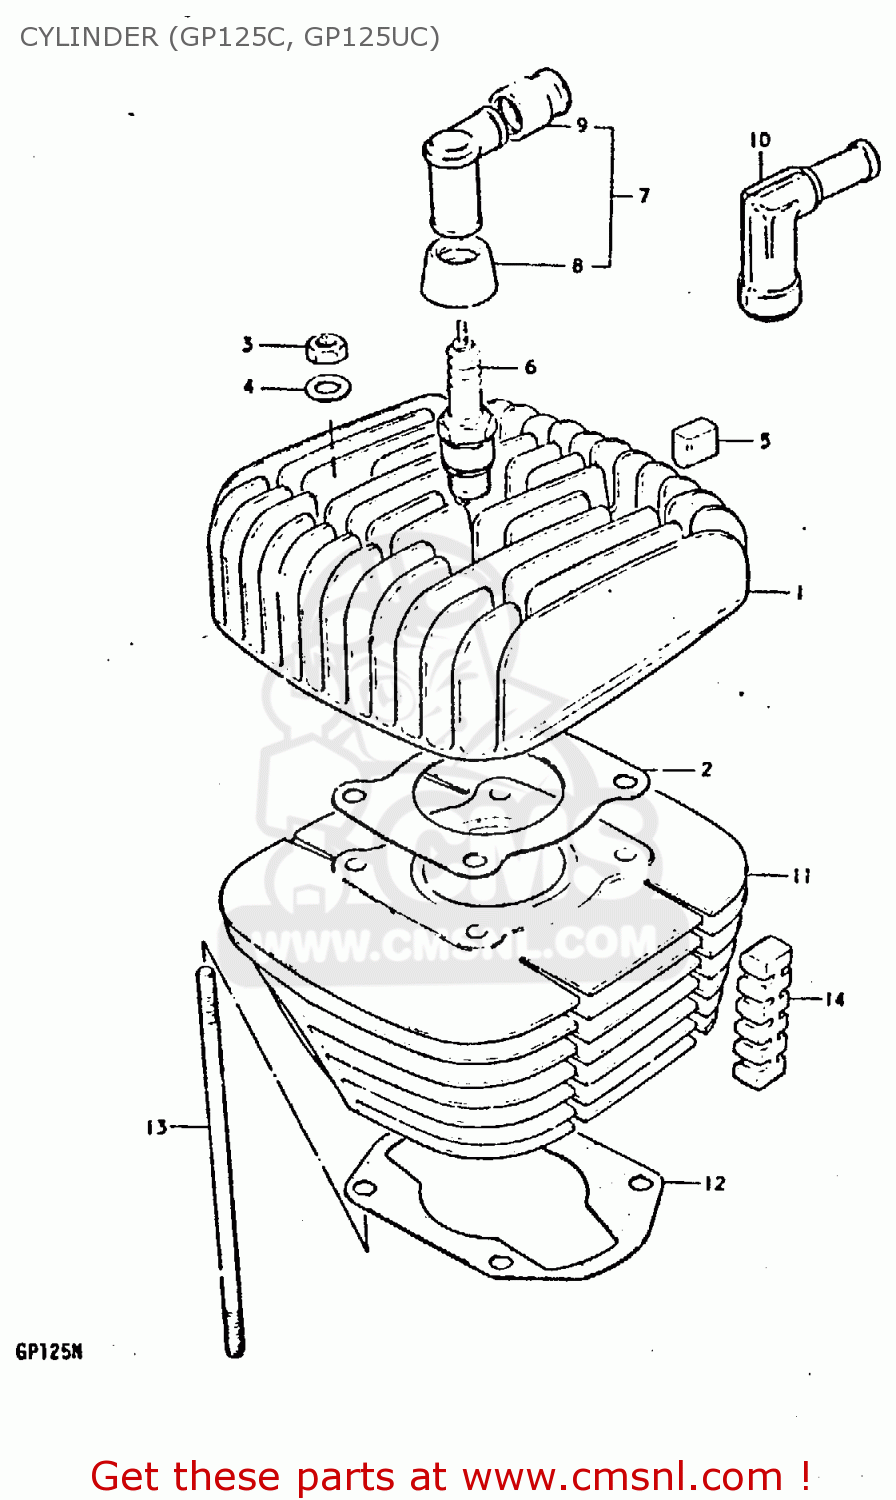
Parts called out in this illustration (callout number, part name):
1	CYLINDER HEAD
2	GASKET (MCA)
3	NUT (8MM)
4	WASHER
5	PAD,CYLINDER
6	SPARK PLUG
9	SEAL,SPARK PLU
10	CAP,SPARK PLUG
11	CYLINDER
12	GASKET, CYLINDER (MCA)
13	BOLT,STUD
14	RUBBER PAD, CYLINDER (1)
